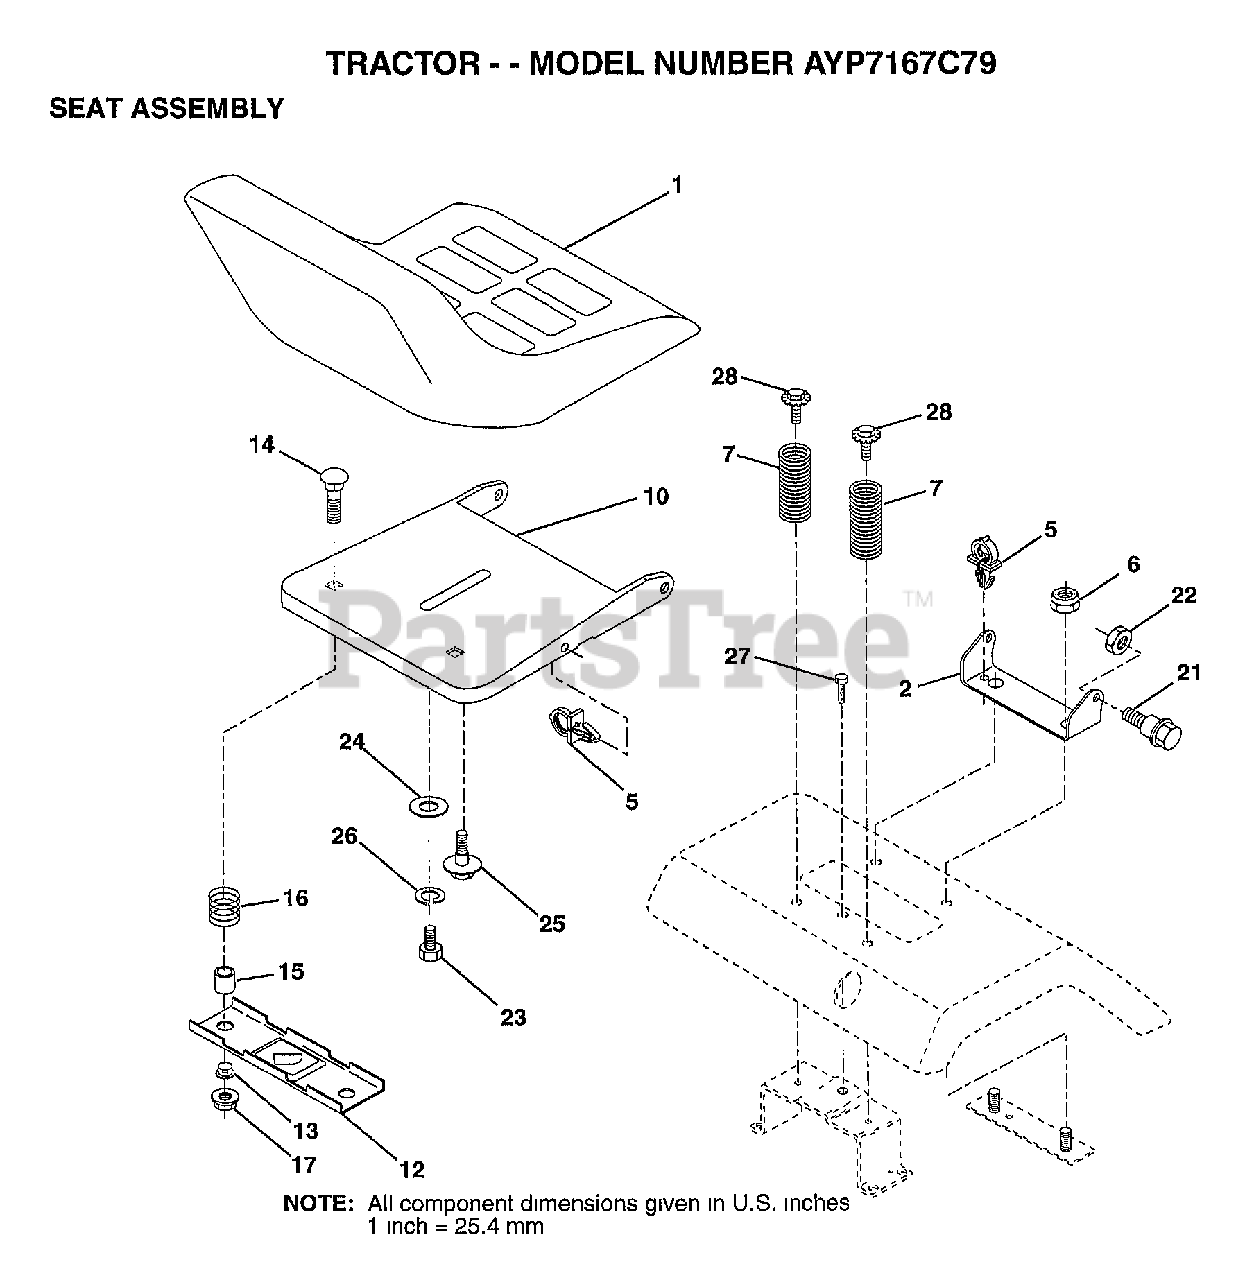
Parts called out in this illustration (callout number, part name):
1	SEAT
2	BRACKET PVT SEAT
5	CLIP.PUSH-IN.HING
6	NUT
7	SPRING COMPRESSIO
10	PAN-SEAT
12	BRKT SWITCH
13	BUSHING
15	SPLIT SPACER
16	SPRING
21	"BOLT,SHOULDER"
22	NUT
23	BOLT
24	WASHER
25	"BOLT,SHOULDER"
26	LOCKWASHER
27	SCREW LT
28	BOLT.5/16-18.UNC
